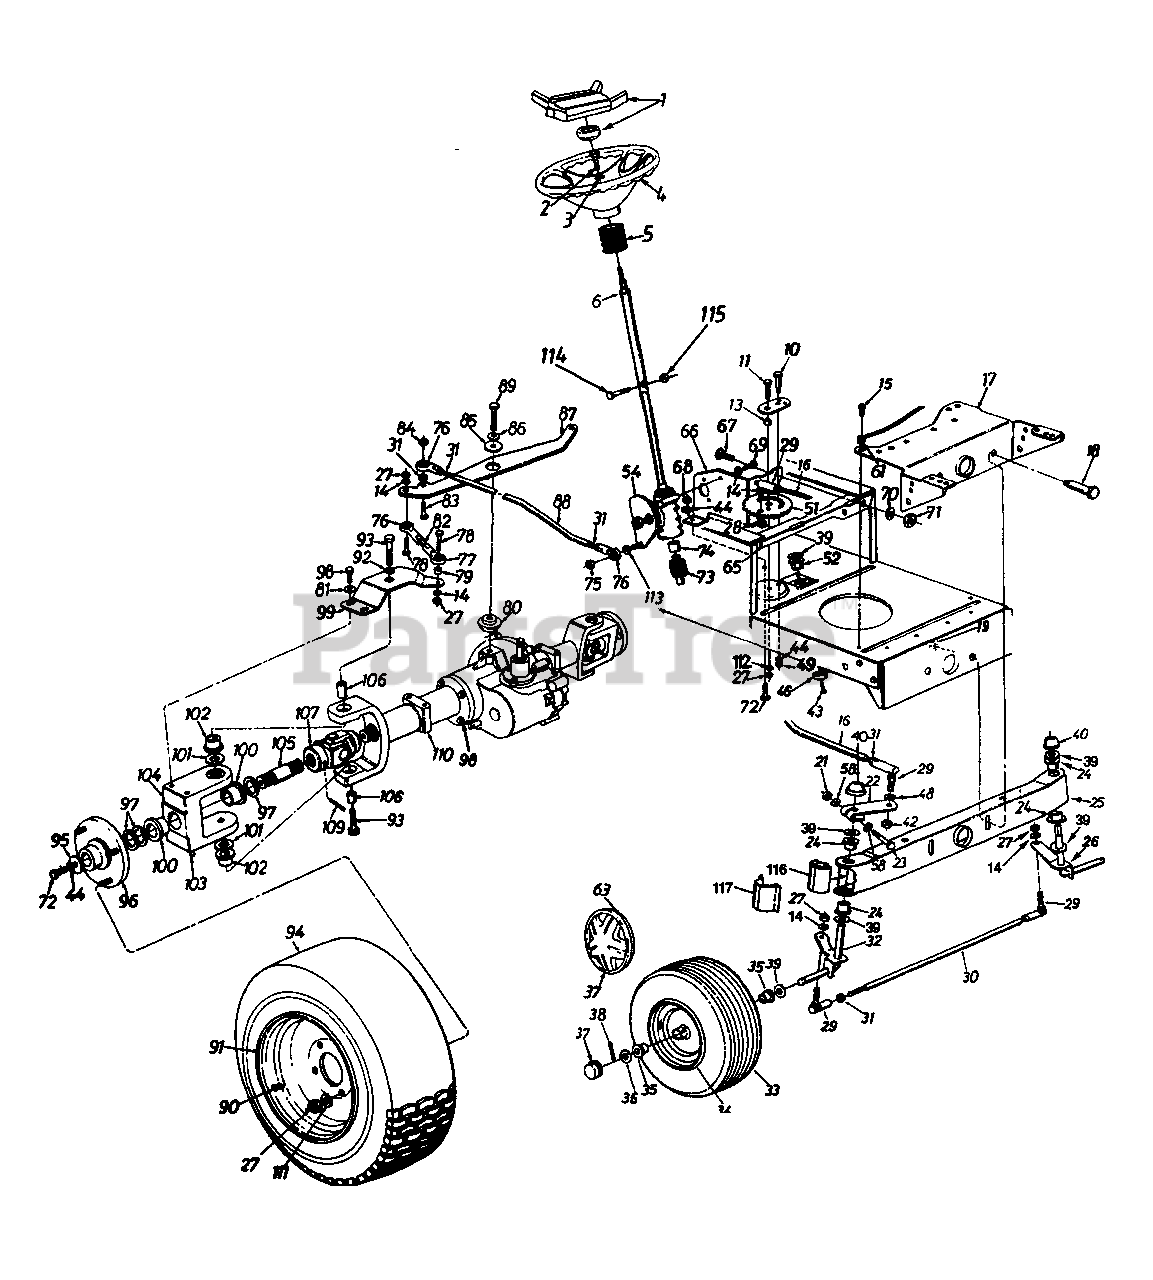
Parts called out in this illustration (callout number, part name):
1	Steering Wheel Insert
2	Hex L-Nut 5/16-24 Thd.
3	Belleville Wash. .345" I.D.
4	Steering Wheel (4 Spoke)
5	Steering Bellow
6	Upper Steering Shaft
10	Shoulder Bolt .437" Dia. x .35" Lg. 5/16-18 Thd.
11	Hex Bolt 3/8-24 x 1.0" Lg. (Grade 5)
13	Spacer .380" I.D. x .625" O.D. x .227"
14	L-Wash. 3/8" I.D.
15	Hex Wash. Hd. Self-Tap Scr.
16	Steering Drag Link
18	Shoulder Bolt .498" Dia. x 2.04" Lg. 3/8-16 Thd.
19	Hex L-Nut 3/8-16 Thd.
21	Hex Cent. L-Nut 5/16-24 Thd.
22	Steering Arm Front Axle
23	Hex Bolt 5/16-24 x 2.00" Lg. (Grade 5)
24	Hex Flg. Brg. .634" I.D.
26	Front Axle Ass'y. - L.H.
27	Hex Nut 3/8-24 Thd.
28	Hex Jam Nut 3/8-24 Thd.
29	Ball Joint 3/8-24 Thd.
30	Tie Rod
31	Hex Jam Nut 3/8-24 Thd.
32	Front Axle Ass'y. - R.H.
33	Wheel Ass'y. Comp.
34	Front Wheel Rim Only
35	Bearing
36	Fl-Wash. .635" I.D. x 1.59" O.D.
37	Front Hub Cap (619)
38	Cotter Pin 1/8" Dia. x 1.25" Lg.
39	Fl-Wash. .640" I.D. x .24" 0.0.
40	Push Cap
43	Pan Hd. Bolt 5/16-18 x .62"
44	L-Wash. 5/16" I.D.
46	Cap
48	L-Wash. 3/8" I.D.
49	Hex Nut 5/16-18 Thd.
51	Steering Gear Segment
52	Hex Flg. Brg. .634 I.D.
54	Steering Box Ass'y. Comp.
58	Wave Wash. .32" I.D. x .62"
61	Ext. L-Wash 5/16" I D.
63	Spring Clip (614)
65	Horizontal Cross Bracket
66	Vertical Mounting Bracket
67	Hex Bolt 1/4-28 x .75" Lg
68	Hex Nut 5/16-24 Thd
69	Hex Bolt 3/8-16 x 1.0" Lg.
70	Bell-Wash 265" I.D. x 75"
71	Hex Nut 1/4-28 Thd.
72	Hex Bolt 5/16-24 x .75" Lg
73	Pinion Shaft
74	Steering Shaft Splined Coupler
75	Hex L-Nut 3/8-24 Thd
76	Rod End 3/8-24 Thd. - R.H.
77	Rod End 3/8-24 Thd. - L.H.
78	Hex Bolt 3/8-24 x 1.5" Lg. (Gr. 5)
79	Spacer .38" I.D. x .625"
80	Shld. Spacer .51" I D.
81	Bell-Wash 38" I.D. x .88"
82	Tie Rod
83	Hex Bolt 3/8-24 x 1.25" Lg.
84	Hex Patch L-Nut 3/8-24 Thd.
85	Fl-Wash. .531" I.D. x 1.75"
86	Bell-Wash .505" I.D. x 1.0"
89	Hex Bolt 1/2-13 x 1.5" Lg (Gr. 5)
90	Air Valve
93	Hex Bolt 1/2-20 x 1.75" Lg. (Gr. 5)
95	Fl-Wash. .33" I D. x 1.25"
96	Wheel Flange Ass'y.
97	Fl-Wash. 1.0" x 1.56"
98	Hex Bolt 3/8-24 x 1 25" Lg.
101	Fl-Wash. .76" I.D. x 1.5"
102	Flange Brg. 3/4" I D.
103	Grease Fltting
104	Wheel Brg. Housing
105	Wheel Flange Ass'y.
106	Pivot Sleeve
107	U-Joint
109	Grooved Roll Pin 1.0" Lg.
110	Axle Horn Ass'y.
111	Bell-Wash. 38" I.D x .88"
112	Bell-Wash. .39" I.D x 1.38"
113	Fl-Wash..385" I.D. x .62"
114	Hex Bolt 1/4-20 x 1.31" Lg.
115	Hex ins. L-Nut 1/4-20 Thd
116	Pivot Bar End Cap
117	Axle Cap
